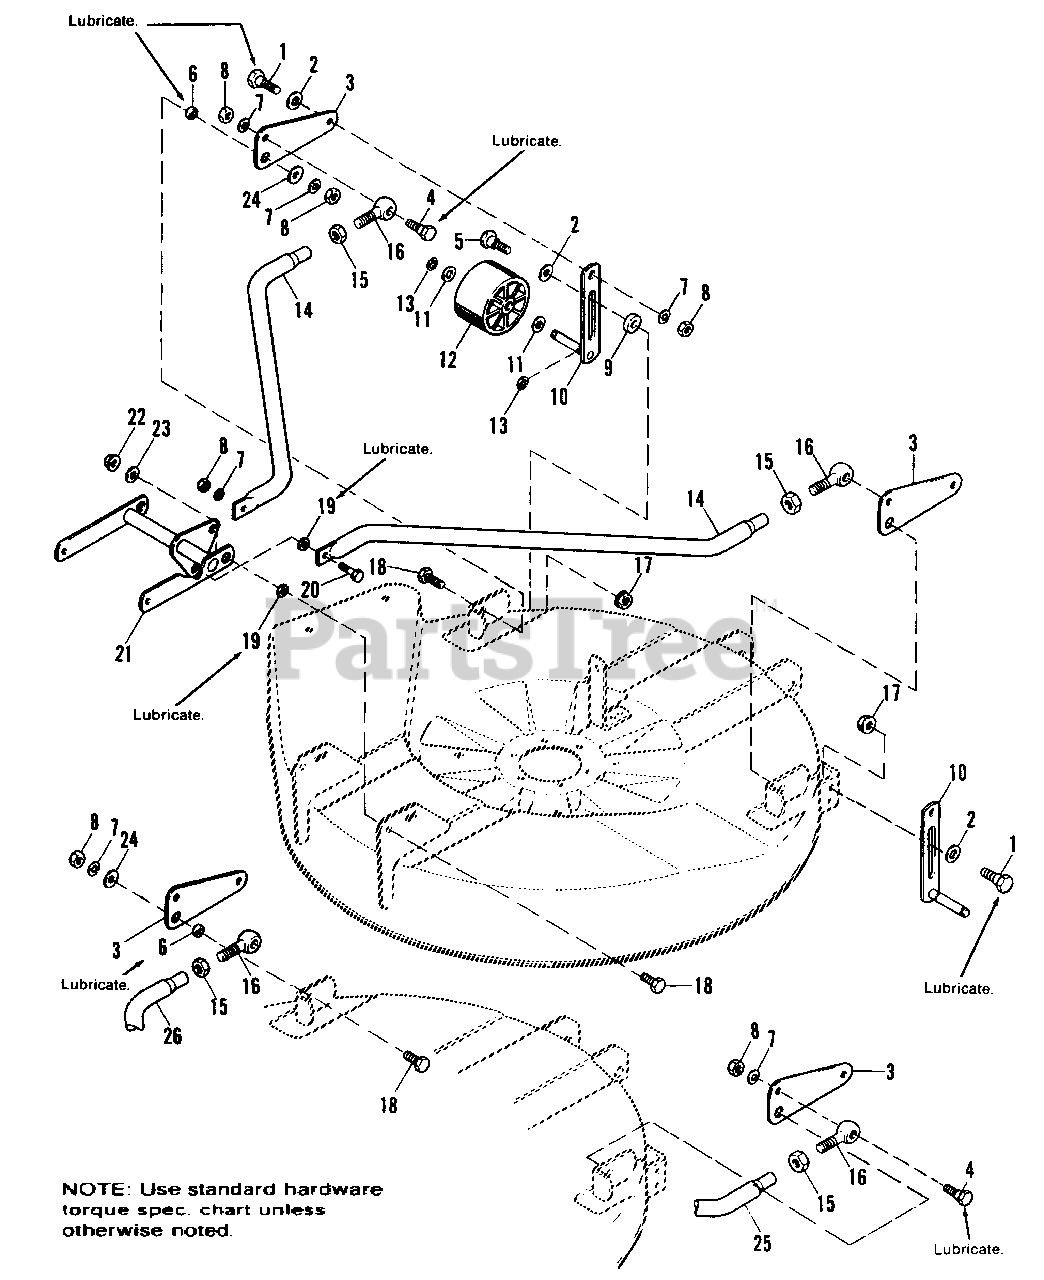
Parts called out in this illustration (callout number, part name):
1	BOLT, Shoulder, 3/8-16 X 1.34
2	WASHER, Plain, 7/16
4	BOLT, Shoulder
5	BOLT, Shoulder, 3/8-16 X 1.34
6	WASHER, Spring
7	LOCKWASHER, 3/8
8	NUT, 3/8-16
9	SPACER (26" Mower Only)
10	ROLLER SUPPORT ASSY.
11	WASHER, Plain, 5/8
13	RING, Retaining
14	ARM, Adjusting (30" Mower Only)
15	NUT, Jam, 1/2-20
17	LOCKNUT, Flange, Whiz, 3/8-16
18	CAPSCREW, Hex, 3/8-16 x 1
20	CAPSCREW, Hex, 3/8-16 x 1-1/4
21	SUPPORT ARM ASSY.
22	LOCKNUT, Flange, Center, 3/8-16
23	WASHER
25	ARM, Adjusting, L.H. (26" Mower Only)
26	ARM, Adjusting, R.H. (26" Mower Only
